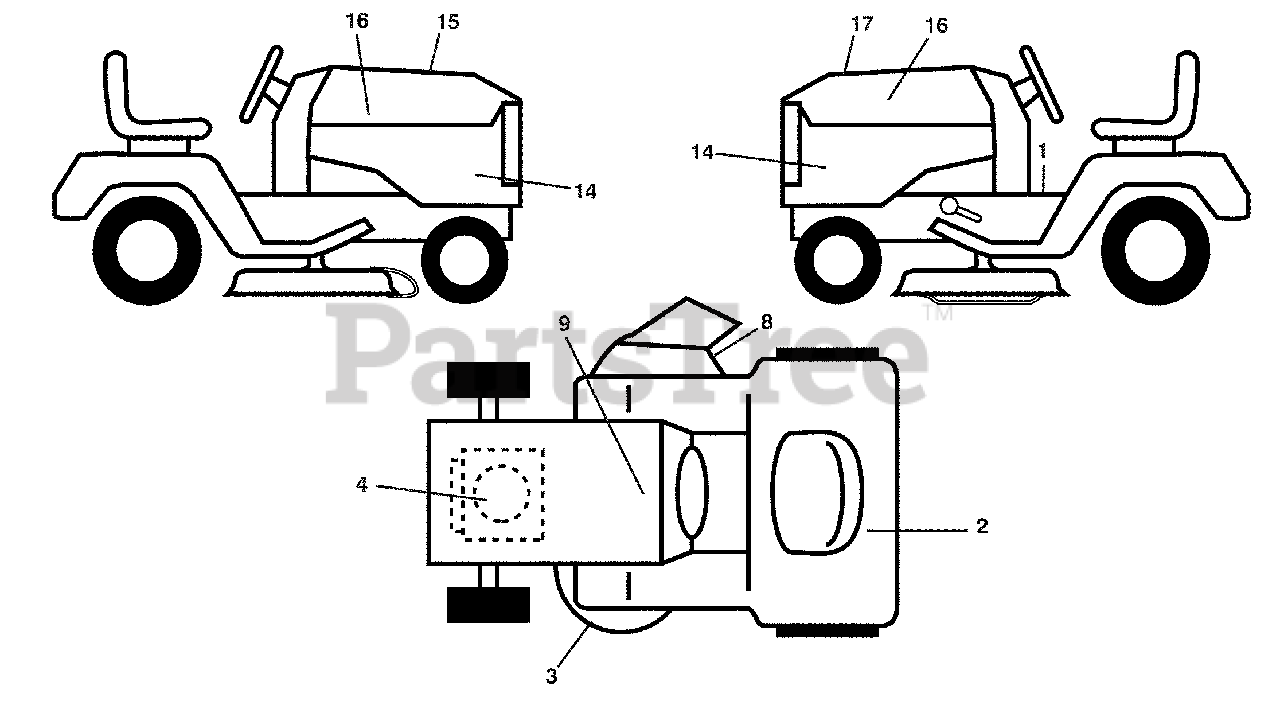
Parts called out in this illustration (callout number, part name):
1	Decal, Warning
2	Decal, Ethanol
3	Decal, Warning
4	Decal, Engine HP
8	Decal, Mower Sch.
9	Decal, Battery Dnge/Poi
14	Decal, Panel Side
15	Decal, Cust. Resp.
16	Decal, Hood Logo
17	Decal, Replacement
